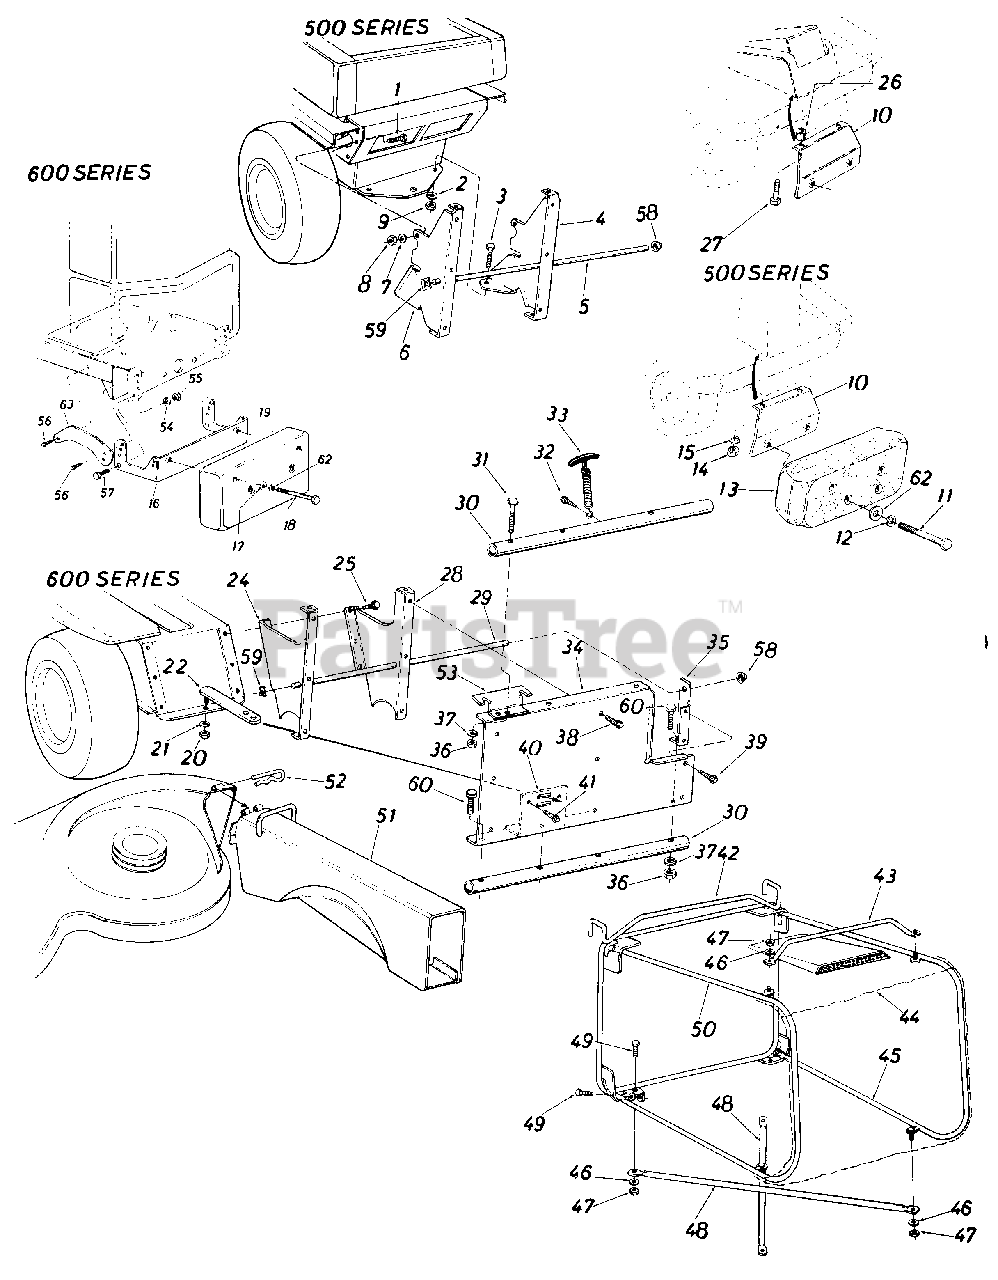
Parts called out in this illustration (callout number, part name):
1	Hex Bolt 5/16-18 x 1.00" Lg.
2	L.-Wash. 5/16" I.D.
3	Hex Bolt 5/16-18 x 1.00" Lg.
4	CatcherSupport Brkt-R.H.
7	L.-Wash. 5/16" I.D.
8	Hex Nut 5/16-18 Thd.
9	Hex Nut 5/16-18 Thd.
10	Counterweight Bracket
11	Hex Bolt 3/8-16 x 4.5" Lg.
12	Belleville Wash..400" I.D. x.88" O.D.
13	Front Counterweight 38 lbs.
14	Hex Nut 5/16-18 Thd.
15	L.-Wash. 5/16" I.D.
16	Counterweight Bracket
17	Belleville Wash. .400" I.D. x.88" O.D.
18	Hex Bolt 3/8-16 x 4.5" Lg.
19	Front Counterweight 38 lbs.
20	Hex Jam Nut 1/2-13 Thd.
21	L.-Wash. 1/2" I.D.
25	Hex Wash. Hd. Self Tap Scr. 5/16-18 x .75 Lg.
26	Spacer .380" I.D. x 1.00" O.D. x .320" Lg.
27	Not Part of Kit
28	Catcher Support Brk't.-R.H
31	Curved Carriage Bolt 5/16-18 x 1.75' Lg.
32	Hex"AB"-Tap Scr. 1/4" x .62" Lg.
33	Hood Latch Ass'y.
34	Grass Catcher Adapter
35	Grass Catcher Support Brkt R.H.
36	Hex Nut 5/16-18 Thd.
37	L.-Wash. 5/16" I.D.
38	Hex Wash. Hd. Self Tap Scr. 1/4-20 x .50" Lg.
39	Hex Wash. Hd. Self Tap Scr. 1/4 20 x .50" Lg.
40	Hitch Bracket
41	Hex Wash. Hd. Self Tap Scr. 1/4-20 x .50" Lg.
42	Grass Bag Frame Ass'y.
43	Grass Catcher Handle 26.75
44	Grass Catcher Bag
47	Hex L.-Nut 1/4-20 Thd.
48	Bottom Cross Brace 30. 36 " Lg.
49	Hex Bolt 1/4-20 x .62" Lg.
52	Not Part of Kit
53	Grass Catcher Support Plate
54	L.-Wash. 7/16" I.D.
55	Hex Nut 7/16-20 Thd.
56	Hex AB Tap Scr. 5/16-18 x 1" Lg.
57	HexBolt 7/16-20x 1.00" Lg.
58	Push Cap
59	Speed Nut
60	Hex Bolt 5/16-18 x 1.75" Lg.
62	Fl.-Wash. .390" I.D. x 1.12" O.D. x .187 Thk.
63	Tie Strap
